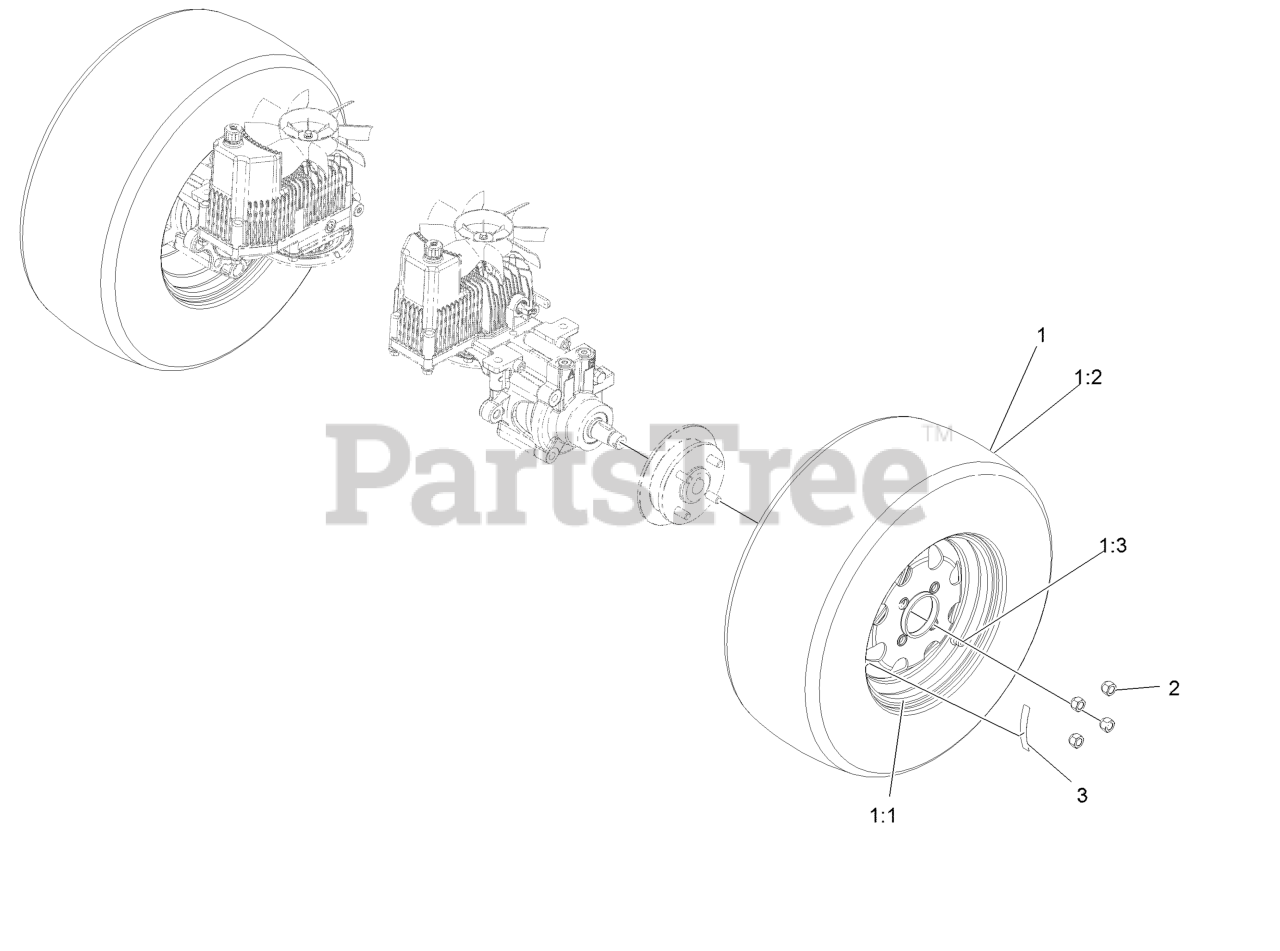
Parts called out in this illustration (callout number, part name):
1	Wheel And Tire ASM
1:1	Rim ASM
1:2	Tire
1:3	Stem-Valve
2	Nut-Lug 1/2-20
3	Decal-Torque, Wheel Hub Lug
